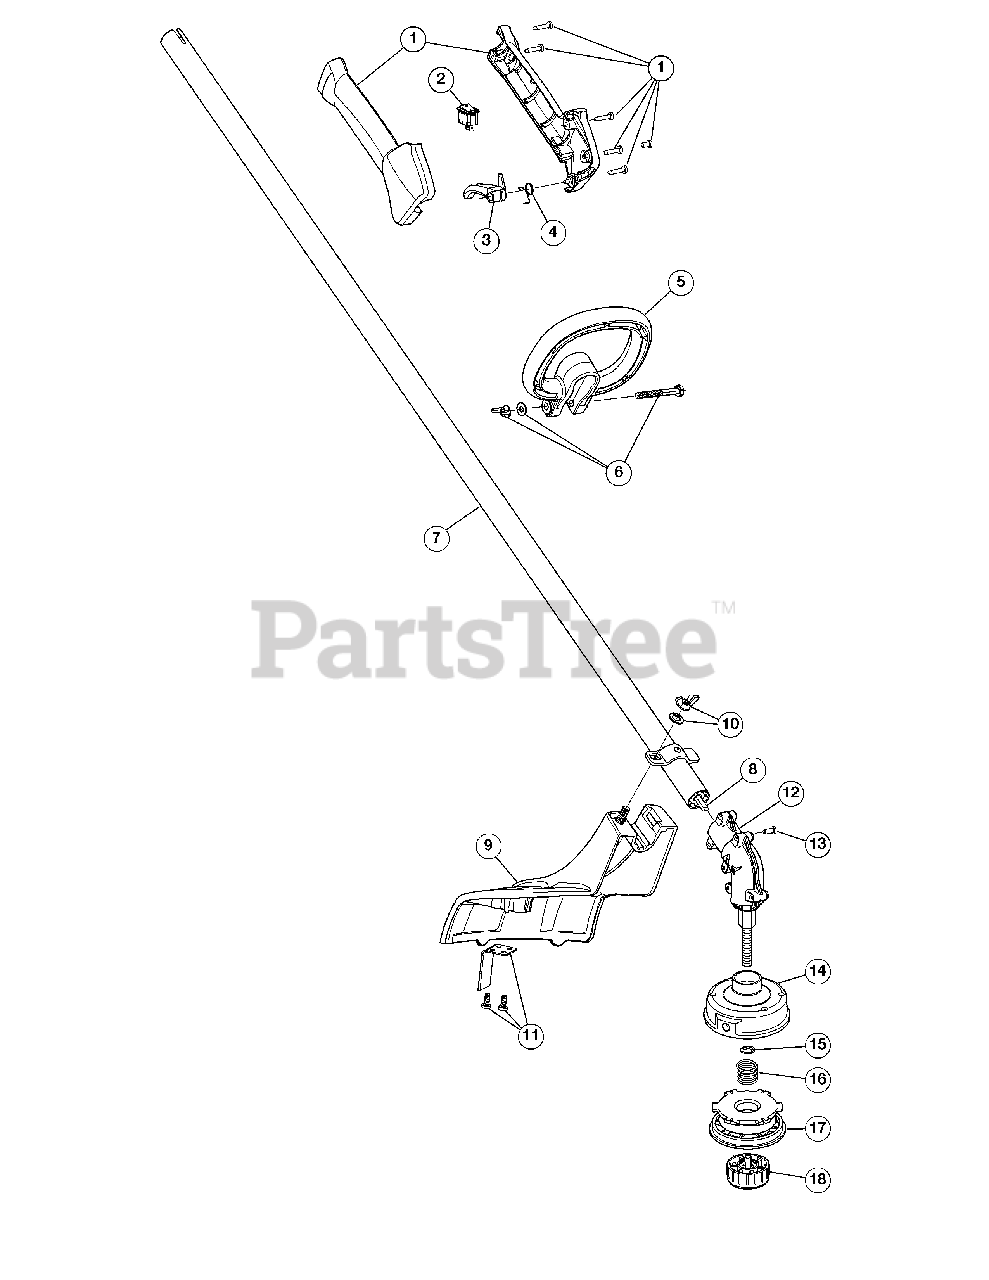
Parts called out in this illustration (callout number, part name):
1	Throttle Housing Assembly (Incl. 2 - 4)
3	Throttle Trigger
4	Throttle Trigger Spring
5	D-Handle (Incl. 6)
6	D-Handle Hardware Assembly
7	Drive Shaft Housing Assembly (Incl. 8)
8	Flexible Drive Shaft
9	Shield Assembly (Incl. 10 & 11)
10	Shield Mounting Hardware
11	Blade Assembly
12	Gearbox Assembly (Incl. 13 - 18)
13	Anti-Rotation Screw
14	Outer Spool Assembly (Incl. 15)
15	Retainer
17	Inner Reel
18	Bump Head Knob Assembly
